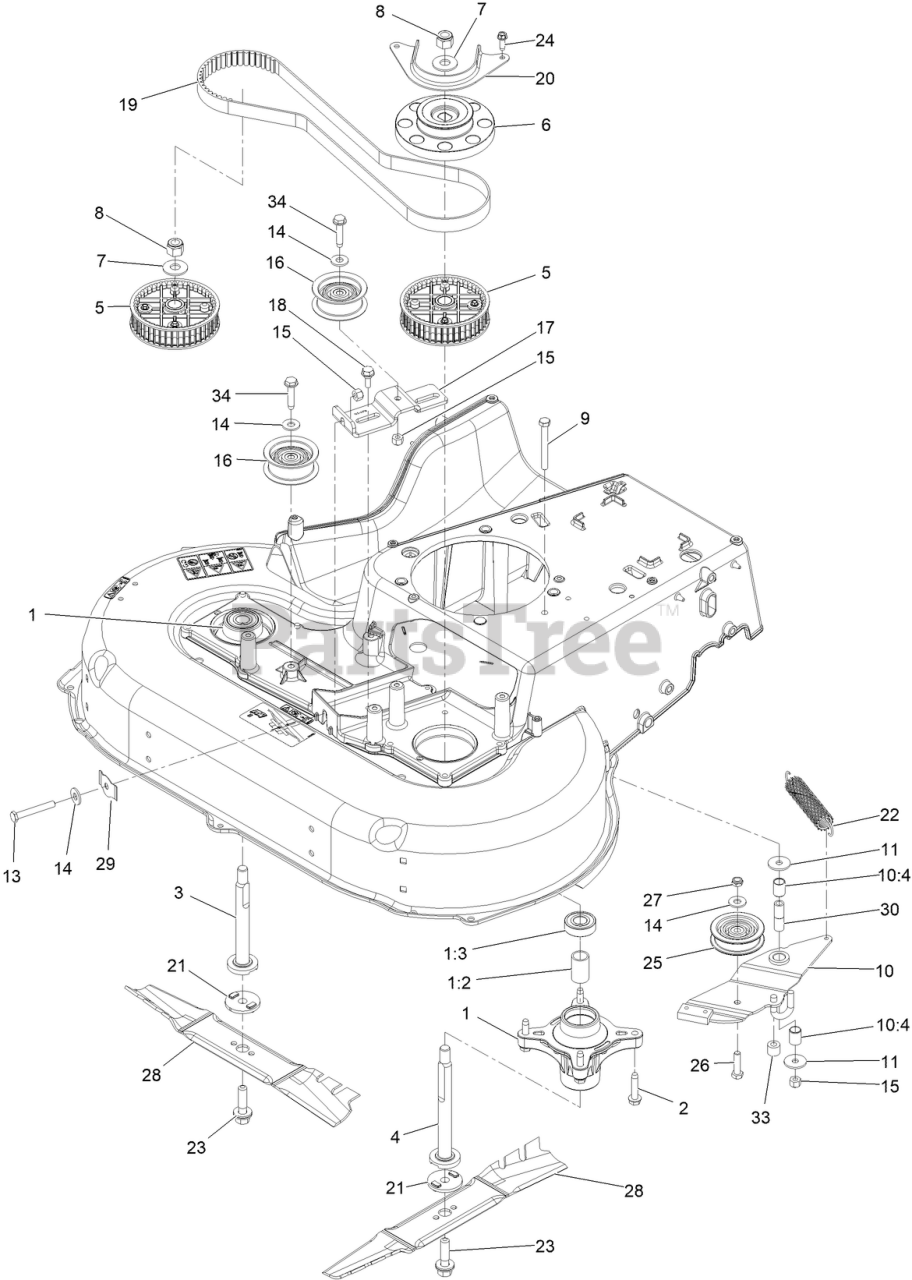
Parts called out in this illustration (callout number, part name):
1	SPINDLE ASM
1:3	BEARING-BALL
2	SCREW-THD ROLL, HWH
3	SHAFT-SPINDLE
4	SHAFT-SPINDLE
5	SPROCKET
6	PULLEY-BRAKE, SPINDLE
7	WASHER-SPRING
8	NUT-HEX
9	SCREW-HH
10	BRAKE ARM ASM
10:4	BUSHING-SLEEVE
11	WASHER-PIVOT
13	BOLT-TAP, HH
14	WASHER-FLAT
15	NUT-LOCK, NI
16	IDLER-PULLEY
17	BRACKET-IDLER
18	SCREW-SHOULDER,HWH
19	BELT-SYNCHRONOUS
20	GUIDE-BELT, SPINDLE
21	ADAPTER-BLADE
22	SPRING-EXTENSION, BRAKE
23	BOLT-BLADE
24	SCREW-HWHTF
25	PULLEY-IDLER
26	SCREW-HH
27	NUT-LOCK, NI
28	BLADE-ROTARY
29	SPRING-FLAT
30	SPACER-BRAKE
33	HOSE-COOLANT
